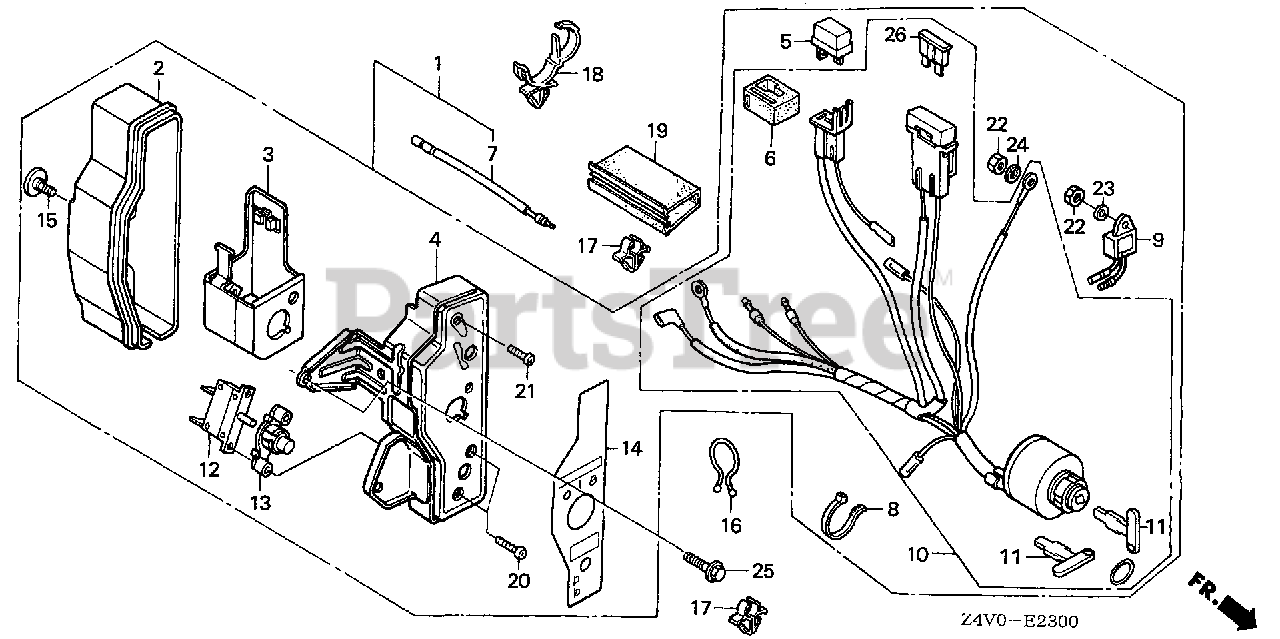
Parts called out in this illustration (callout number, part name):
1	BOX ASSY., CONTROL *R280* (EXP-ALERT) (POWER RED)
2	CASE, CONTROL
3	BRACKET, CASE MOUNTING
4	PANEL, CONTROL *R280* (POWER RED)
5	RECTIFIER ASSY., SILICON (SHINDENGEN)
6	SUSPENSION, CONNECTOR
7	SUB-WIRE HARNESS
8	BAND
9	ALERT UNIT, OIL
10	SWITCH ASSY., COMBINATION
11	KEY
12	PROTECTOR, CIRCUIT (1.0A)
13	LENS ASSY., PROTECTOR
14	MARK, CONTROL BOX (EXTERNAL)
15	SCREW, SPECIAL (6X12)
16	CLIP, PURSE LOCK
17	CLIP, CORD
18	STRAP, WIRE HARNESS (25MM) (BLACK)
19	TUBE, FASTENER (30)
20	SCREW, PAN (3X12)
21	SCREW, PAN (4X12)
22	NUT, HEX. (4MM)
23	WASHER, PLAIN (4MM)
24	WASHER, SPRING (4MM)
25	BOLT, FLANGE (6X10)
26	FUSE, BLADE (5A)
